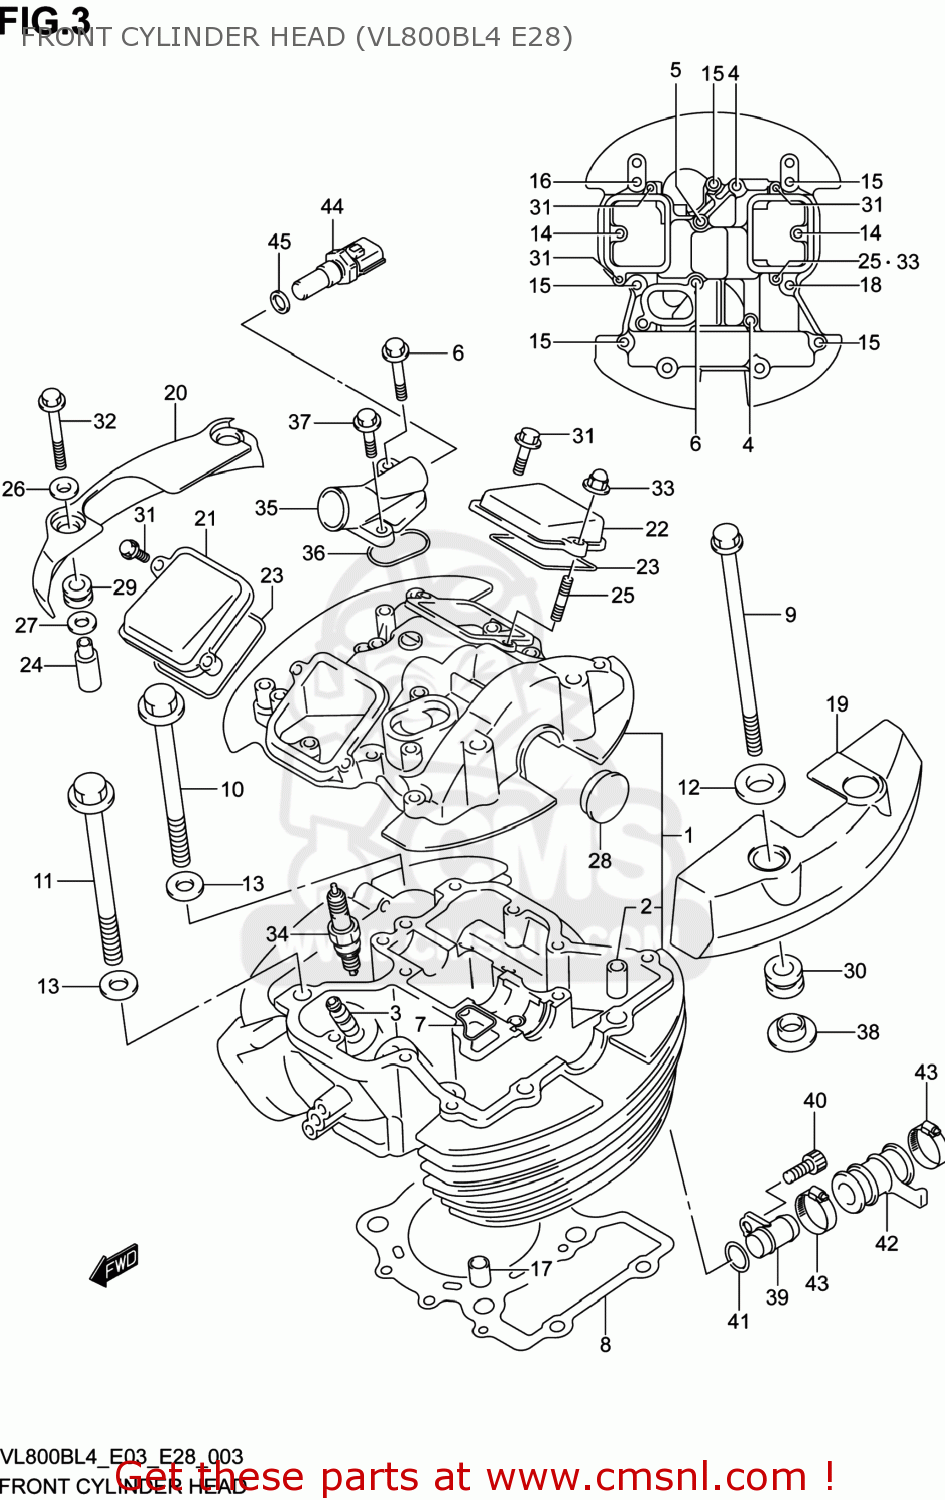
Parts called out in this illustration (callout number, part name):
1	HEAD ASSY,CYLINDER FR
2	PIN(11X14)
3	GUIDE,VALVE(OS:0.3)
4	BOLT(6X50)
5	BOLT(6X55)
6	BOLT
7	GASKET,CYLINDER HEAD WATER (NAS)
8	GASKET,CYLINDER HEAD FR (NAS)
9	BOLT(8X250)
10	BOLT(10X155)
11	BOLT(10X165)
12	WASHER(8.5X24X1.6)
13	WASHER(10.5X22X2.3)
14	BOLT
15	BOLT
16	BOLT
17	PIN
18	BOLT
19	CAP,CYLINDER HEAD COVER FR,L
20	CAP,CYLINDER HEAD COVER FR
21	CAP,INSPECTION INTAKE
22	CAP,INSPECTION EXHAUST
23	GASKET,INSPECTION CAP (NAS)
24	SPACER,CYL HEAD COVER CAP NO.2
25	BOLT,STUD
26	WASHER(6.5X18X1.6)
27	WASHER(9.5X20X1)
28	PLUG(OD:30)
29	CUSHION
30	CUSHION
31	BOLT
32	BOLT
33	NUT
34	PLUG,SPARK(DPR7EA-9)
35	UNION,CYL HEAD OUTLET
36	GASKET,WATER OUTLET UNION (NAS)
37	BOLT
38	BUSH
39	UNION,CYL HEAD JOINT
40	BOLT
41	O RING(D:2.4,ID:15.8)
42	HOSE,CYLINDER HEAD JOINT
43	CLAMP
44	SENSOR,WATER TEMP
45	GASKET(12X17X1) (NAS)
